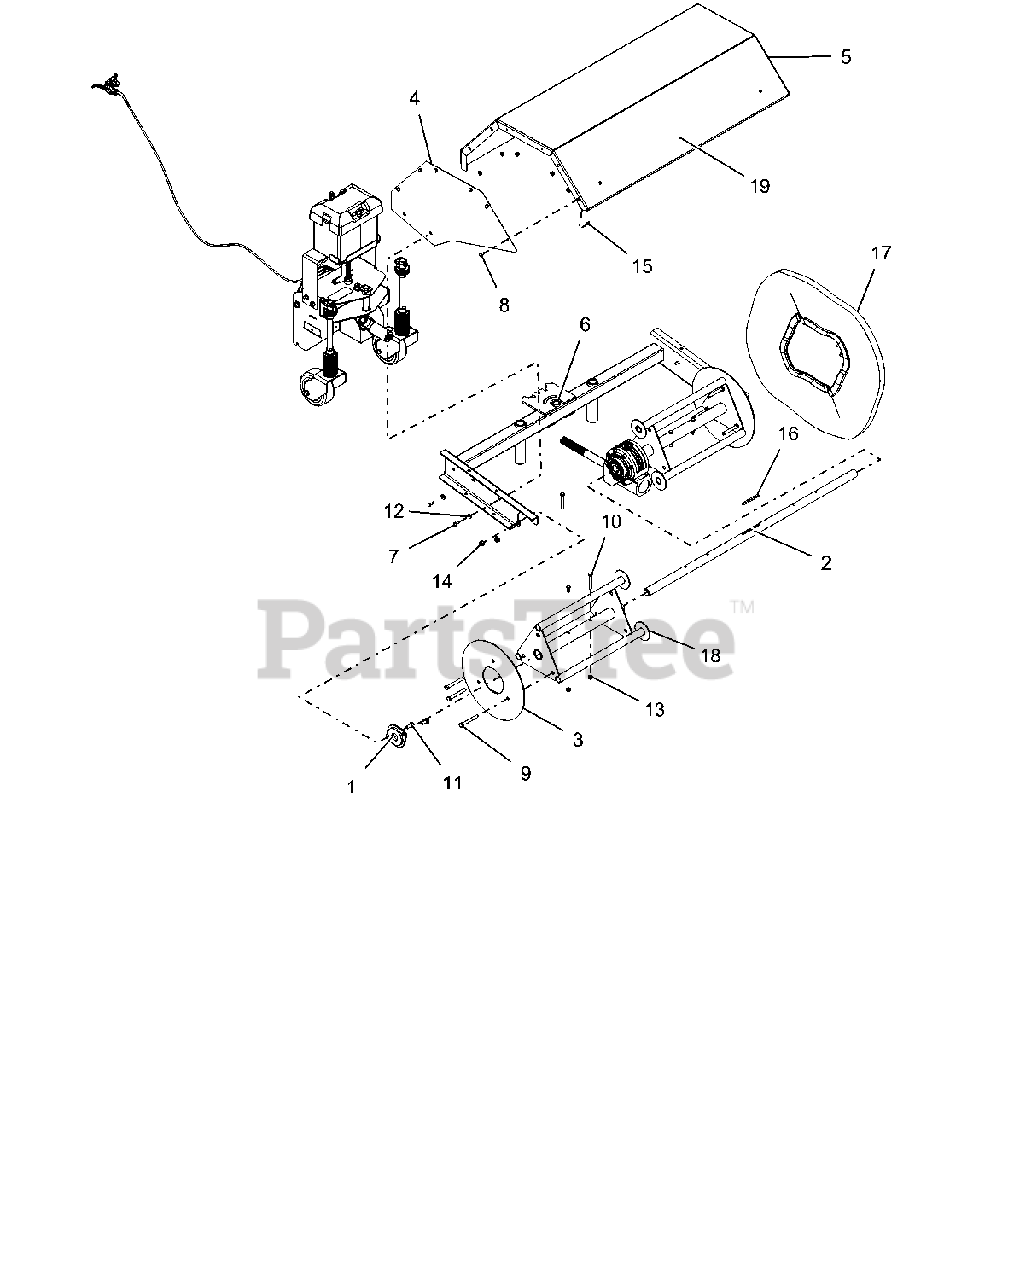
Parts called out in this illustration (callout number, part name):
1	BEARING,2 BOLT FLANGE 1-1/8 ID
2	CENTER, SHAFT
3	PLATE, END RETAINER
4	WLDT, SIDE COVER - RH
5	WLDT, SIDE COVER - LH
6	FRAME, POWER BROOM 36"
7	@BLT-HEX .25-20X.75 GR5 YWZC
8	@BLT-HEX .25-20X.50 GR5 YWZC
9	BLT-HEX .38-16X3.00 GR5 FTH YZ
10	@BLT-HEX .31-18X2.25 GR5 YWZC
11	@BLT-RDHDSQNK .38-16X1.00 G5YZ
12	@WSHR-FL-STL.312X.734X.065 YWZ
13	@NUT-LK-CTR .31-18 YWZC
14	@NUT-LK-TOP-FLG .38-16 YWZC
15	@NUT-LK-TOP-FLG .25-20 YWZC
16	KEY .25 X .25 X 3IN
17	KIT, BRISTLE - SET OF 18
18	PB36 DRIVE CORE SERVICE KIT
19	COVER, TOP - 36" BRUSH W/DECAL
